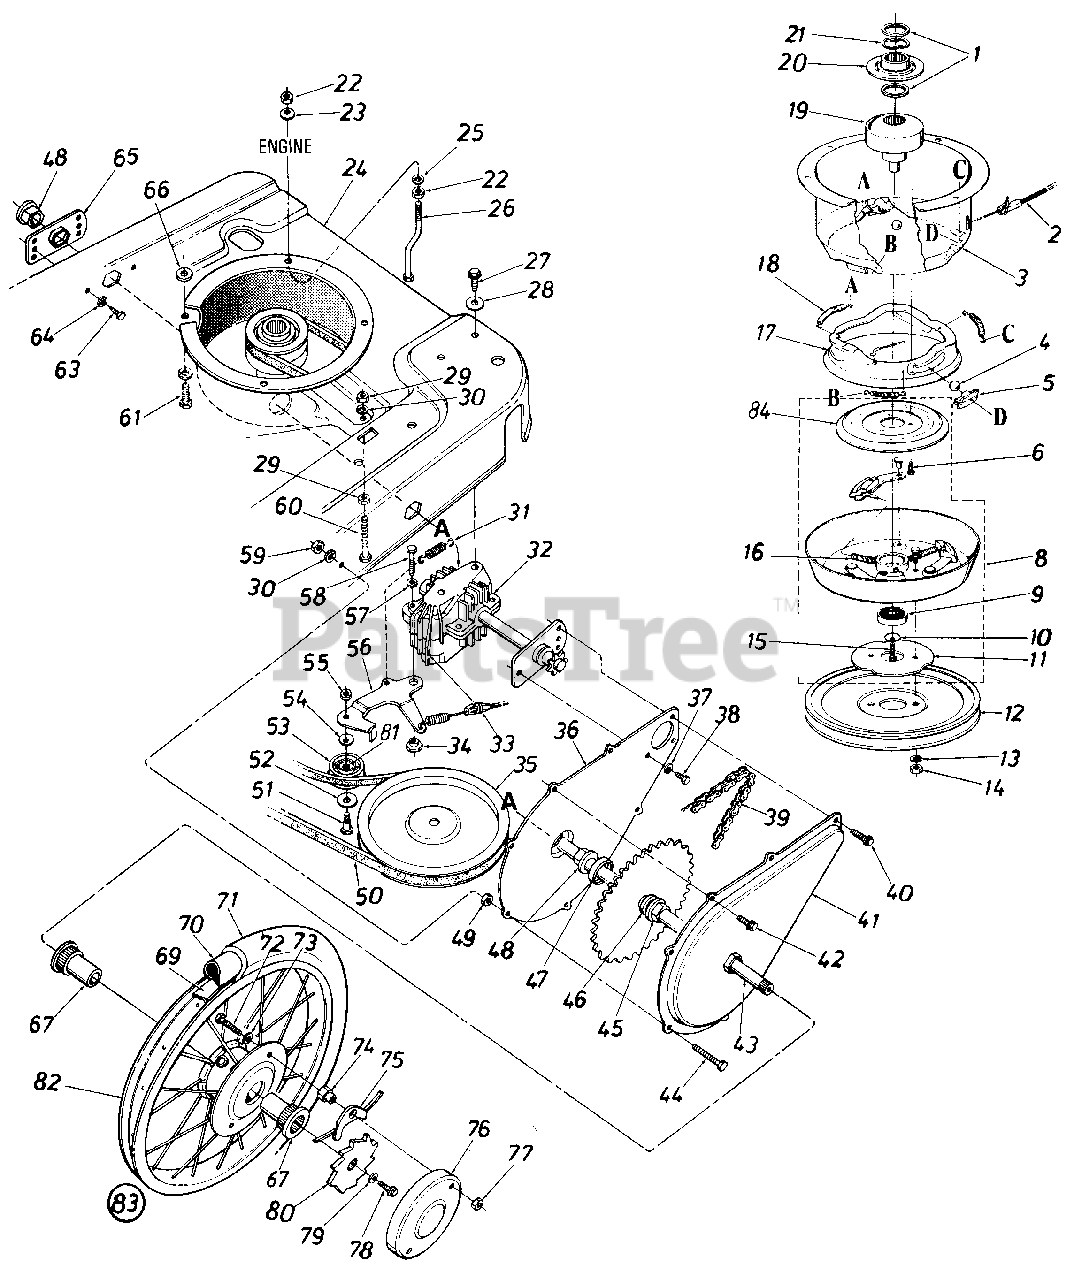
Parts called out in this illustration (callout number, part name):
1	Washer 1.0" I.D. x 1.2" O.D.
2	BBC Clutch Cable 46" Lg.
3	Clutch Housing
4	Steel Ball .500" Dia.
5	Ball Block
6	Hex Wash. TT-Tap Cl. Scr. 1/4-20 x .50" Lg.
8	Clutch Blade Housing Ass'y.
9	Ball Brg. .669" I.D. x 1.574" O.D.
10	Bell-Wash. .44" I.D. x .87" O.D.
11	Blade Disc.
12	5/8 "V"-Pulley 1.58" I.D. x 8.0" O.D.
13	L-Wash. 3/8" I.D.
14	Hex Nut 3/8-24 Thd.
15	Hex Bolt 7/16-20 x 2.0" Lg.-Gr. 5
16	Comp. Spring .33" O.D. x 2.05" Lg.
17	Brake Cup Cone
18	Extension Spring .35" O.D. x 1.80" Lg.
19	Fixed Pulley MBC Adapter
20	Movable Pulley Half
21	Wave Wash. .164 High x 1.005" I.D.
22	Hex Nut 5/16-18 Thd.
23	Bell-Wash. .336" I.D. x .860" O.D.
24	Hi-Wheel Frame
25	L-Wash. 5/16" I.D.
26	Belt Guard 5/16" Bolt
27	Hex Wash. Hd. B-Tap Scr. 5/16-18 x .50" Lg.
28	Bell-Wash. .400" I.D. x 1.13" O.D.
29	Hex Nut 1/4-20 Thd.
30	L-Wash. 1/4" I.D.
31	Extension Spring .33" I.D. x 1.12" Lg.
32	Transmission Comp.
33	Self-Propelled Cable x 501' Lg .-Black
34	Shld. Spacer .375" Dia. x . 1 70
35	Fl-Pulley 5.06" O.D.
36	45 Tooth Chain Cover
37	L-Wash. 1/4" I.D.
38	Hex B-Tap Scr. 1/4 x .38" Lg.
39	#48 Chain .500" Pitch x 52 Links
40	Hex Wash. TT-Tap Scr. 1/4-20 x .50" Lg.
41	45 Tooth Chain Case
42	Hex B-Tap Scr. 1/4 x .38" Lg.
43	Rear Axle Ass'y. 26.82" Lg.
44	Hex Bolt 1/4-28 x .88" Lg.
45	Hex Flange Brg. .631" I.D. x .320
46	Fl-Wash. .635" I.D. x 1.0" O.D.
47	Spacer .630" I.D. x 1.250" O.D.
48	Hex Flange Brg. .631" I.D. x .720
49	Hex Jam Nut 1/4-28 Thd.
50	"V"-Belt
51	Shld. Bolt .375" Dia. x .400 Lg.
52	Fl-Wash. .390" I.D. x 1.00" O.D.
53	Fl-Idler Plastic 1.50" Dia. x .48
54	Bell-Wash. .265" I.D. x .75" O.D.
55	Hex Nut 1/4-28 Thd.
56	Idler Brk't. Ass'y.
57	L-Wash. 1/4" I.D.
58	Hex Bolt 1/4-20 x 1.25" Lg.
59	Hex Nut 1/4-28 Thd.
60	Hex Bolt 1/4-20 x 2.00" Lg.
61	Hex Wash. Hd. TT-Tap Scr. 3/8-16 x 1.0" Lg.
63	Hex B-Tap Scr. 1/4 x .38" '.g.
64	L-Wash. 1/4" I.D.
65	Hex Bearing Cup
66	Fl-Wash. .406" I.D. x .734 O.D.
67	Flange Bearing .630" I.D. x 2.83" Lg.
69	Rimstrip 16 x 7/8
70	Inner Tube 16 x 2.12
71	Chevron Tire 16 x 2.125
72	Hex Bolt Special 5/16-18 x 1.0" Lg.
73	Intern. L-Wash. 5/16" I.D.
74	Special Hex Nut 5/16-18 Thd.
75	Pawl & Spring Ass'y.
76	Wheel Cover 4.75" I.D.
77	Hex Nut 5/16-18 Thd.
78	Hex Wash. Hd. Self-Tap Screw 1/4" x 3/4" Lg.
79	Bell-Wash. .265" I.D. x .75" O.D.
80	Wheel Ratchet 2.92" O.D.
81	Needle Brg. .375" x .31"
82	Rim Ass'y. Only 16.0" x 2.1
83	Wheel Ass'y. Comp. 16 x 2.12
84	Clutching Cone
